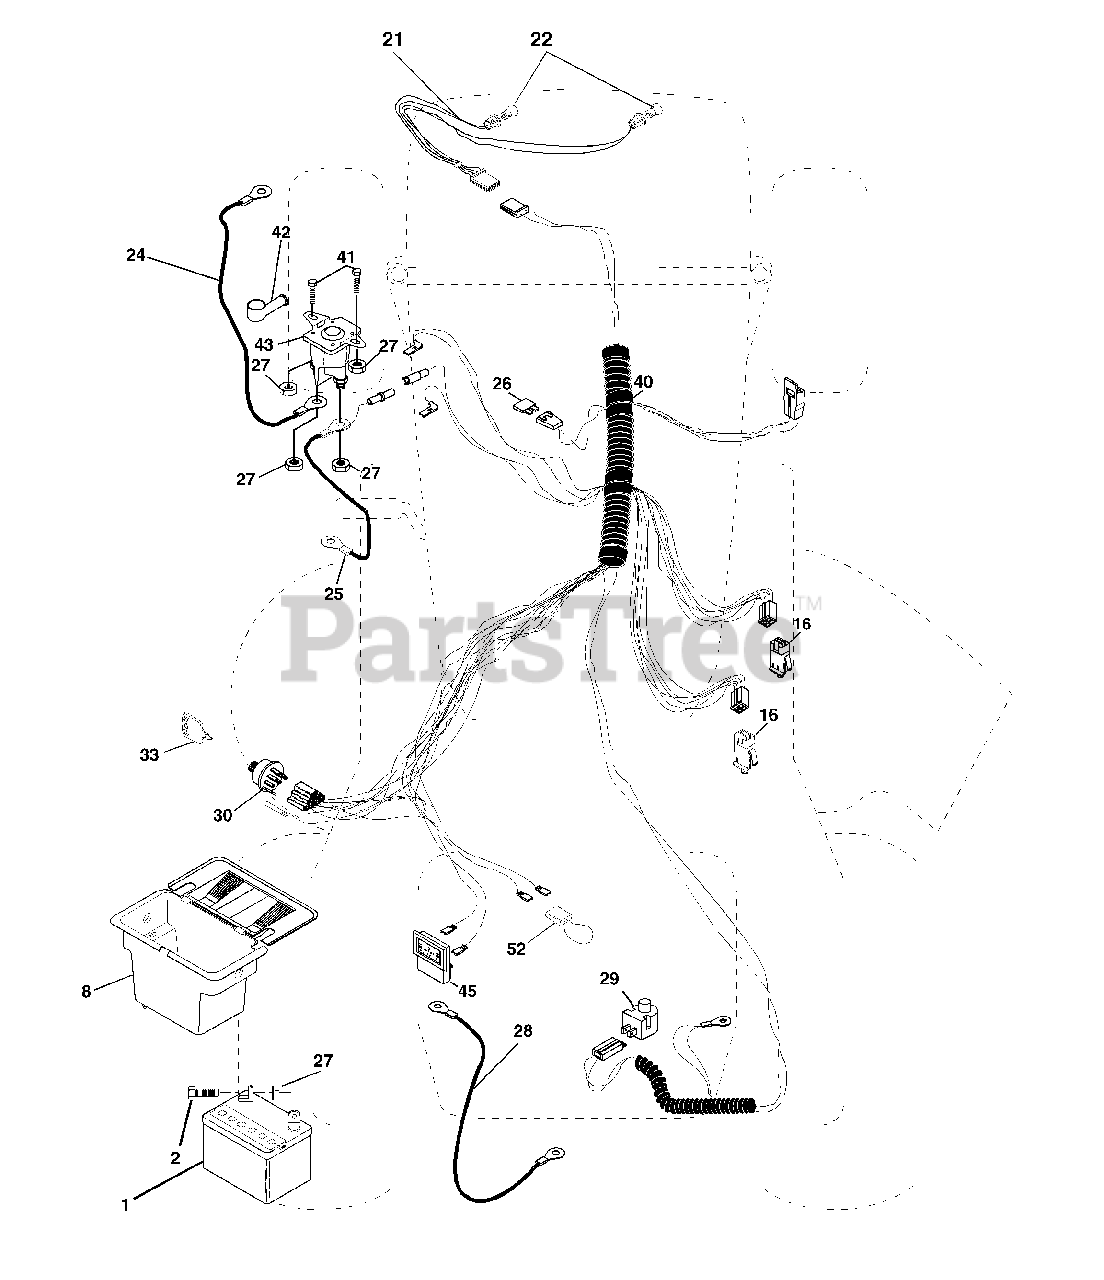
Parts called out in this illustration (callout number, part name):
1	Battery 12 Volt 25 Amp
2	Bolt Hex Hd 1/4-20unc X 3/4
8	Case Battery
16	Switch Interlock Push -In
21	Harness Asm Light W/4152J
22	Bulb Light #1156
24	Cable Battery 6 Ga 11"red
25	Cable Battery 6 Ga w/16 wire,red
26	Fuse 20 AMP
27	Nut Keps Hex 1/4-20 unc
28	Cable Ground 6 Ga 12" black
29	Switch Plunger Nc Gray
30	Switch Ign
33	Key Ign
40	Harness Ign
41	Bolt Blk Fin Hex 1/4-20 X 1/2
42	Cover Terminal Red
43	Solenoid
45	Ammeter
52	Protection Wire Loop
